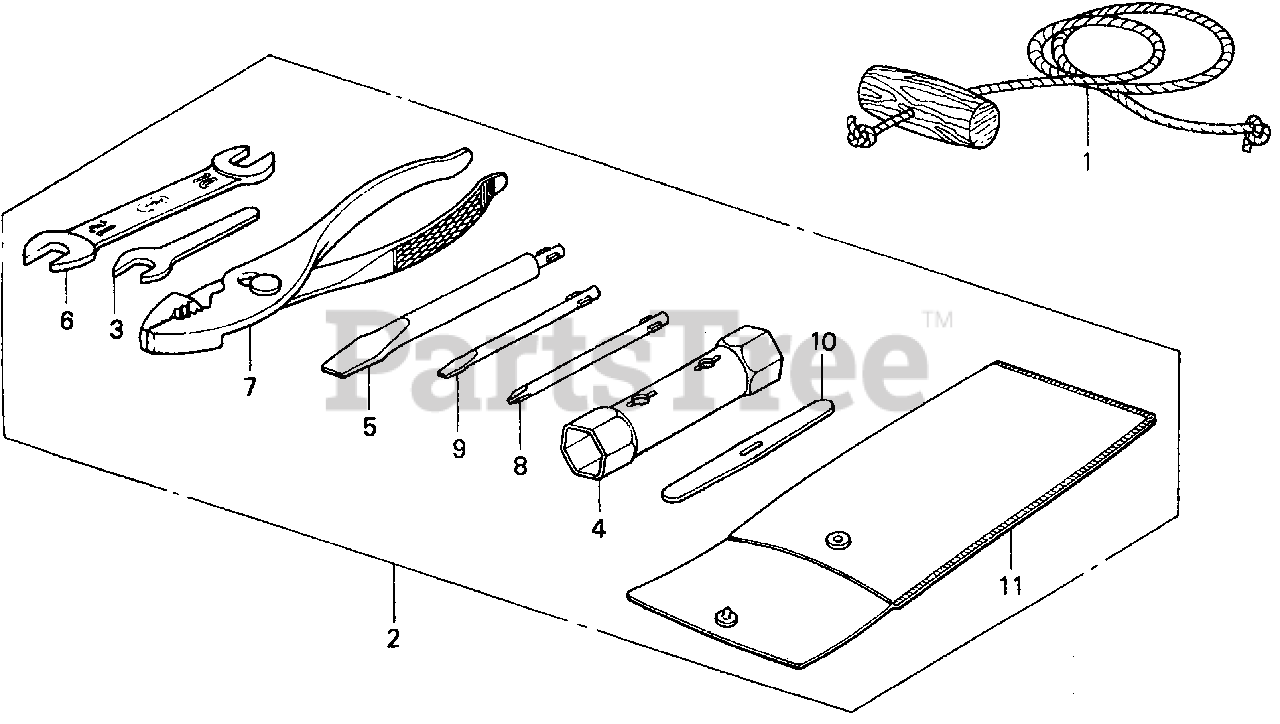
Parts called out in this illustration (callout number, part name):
1	ROPE, STARTER (#5X55")
2	TOOL KIT
3	WRENCH (8MM) (OPEN END) (NOT AVAILABLE)
4	WRENCH, BOX (P18X19) (NOT AVAILABLE)
5	SCREWDRIVER, CHECK BOLT
6	WRENCH (10X12) (OPEN END)
7	PLIERS (135MM)
8	SCREWDRIVER 1, PHILLIPS (NO.2)
9	SCREWDRIVER 3, STRAIGHT SLOT (NO.2)
10	LEVER, TIRE
